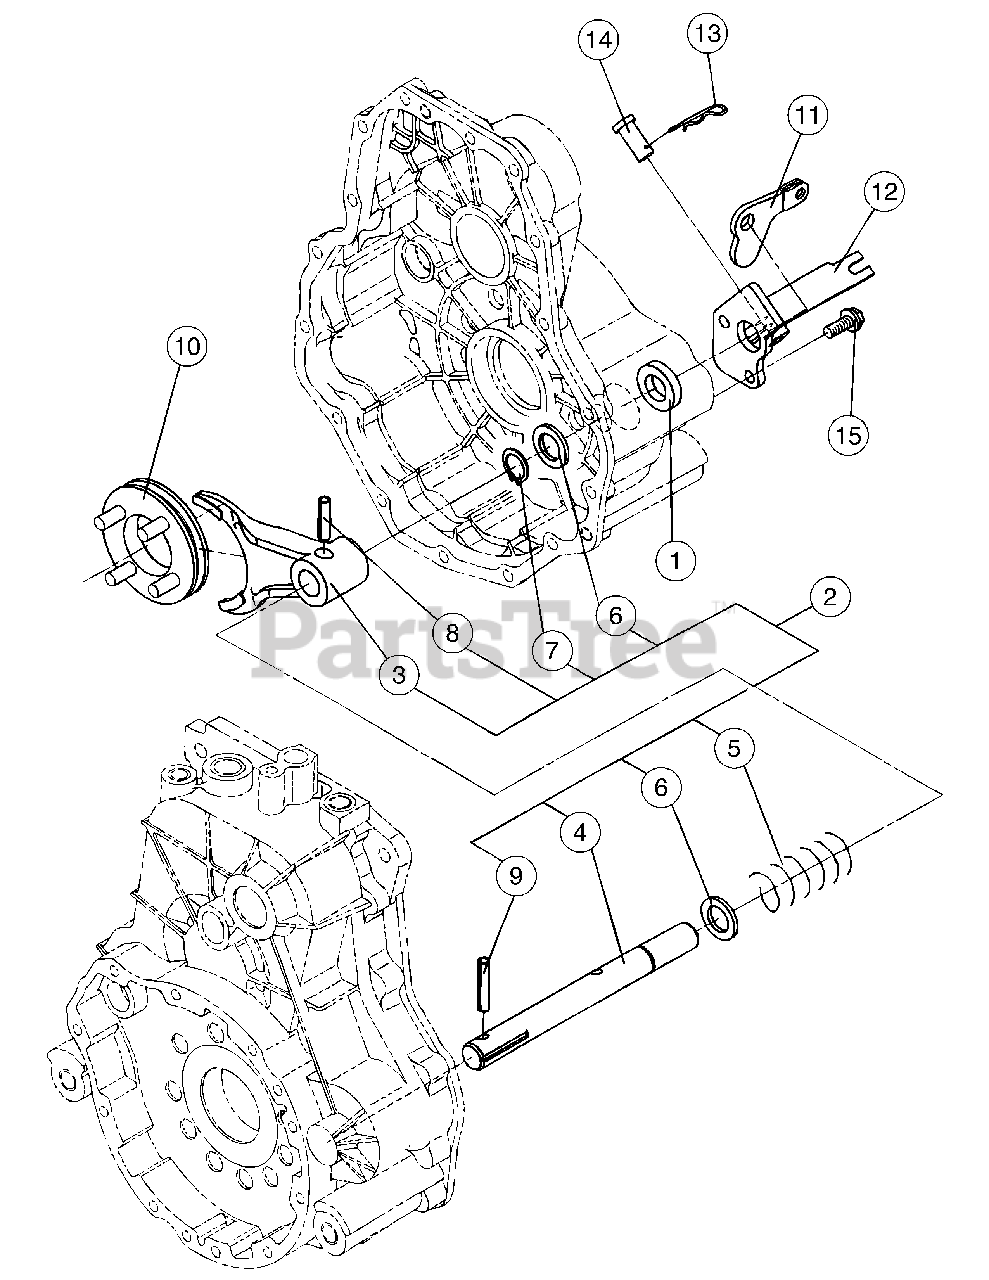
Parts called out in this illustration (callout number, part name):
1	Seal, TC4 20 35 7
2	Differential Lock Kit
3	Fork, Differential Lock
4	Shaft, Differential Lock
5	Spring, Differential Lock
6	Spacer, 20 x 32 x 3.2
8	Pin, 8.0A x 32
9	Pin, 8.0A x 40
10	Slider, Differential Lock
11	Arm, Differential Lock
12	Bracket, Differential Lock
13	Pin, 12
15	Tapping Screw, 8 x 20
15	Flange Bolt, M8 x 20
